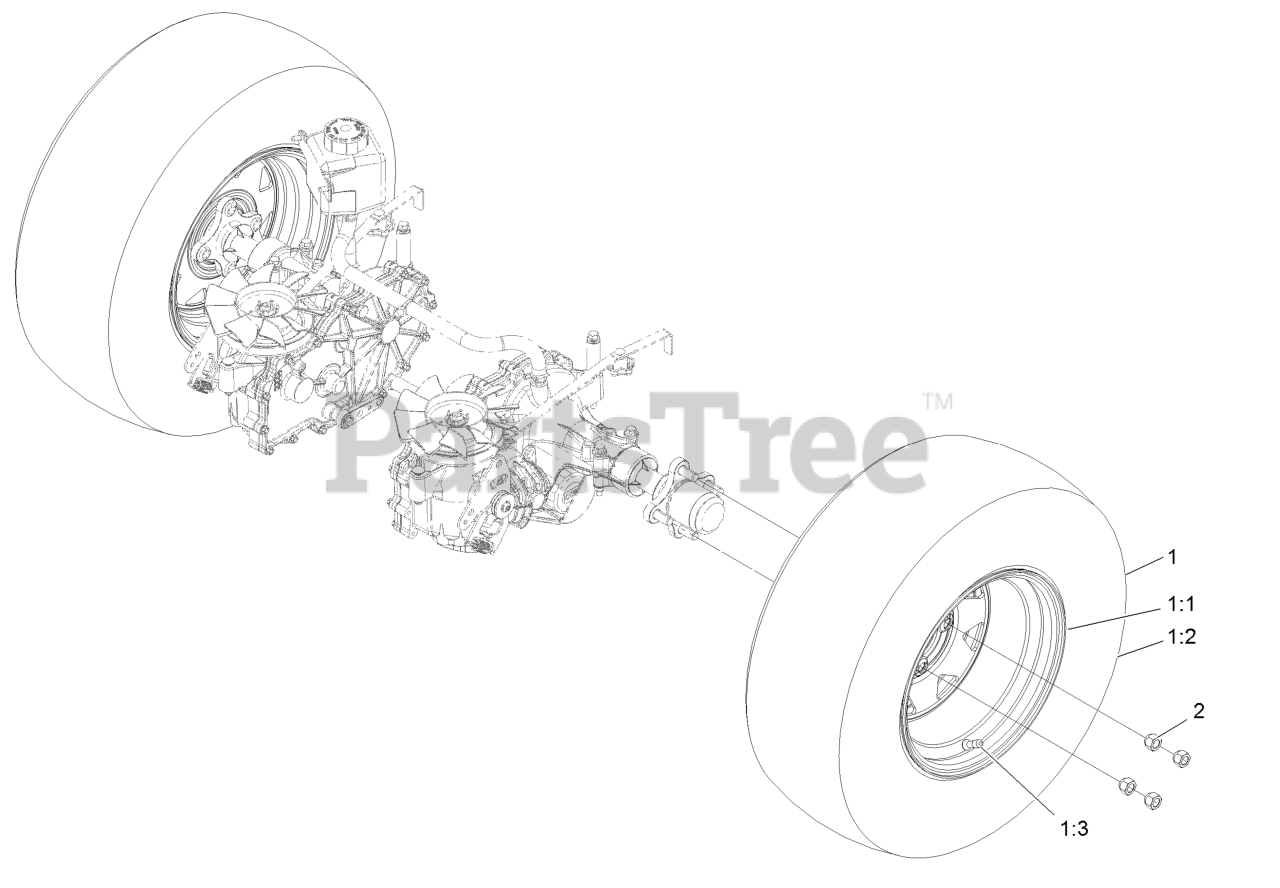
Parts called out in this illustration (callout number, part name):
1	Wheel And Tire ASM
1:1	Wheel Rim 12X8.5
1:2	Tire
1:3	Stem-Valve
2	Nut-Lug
